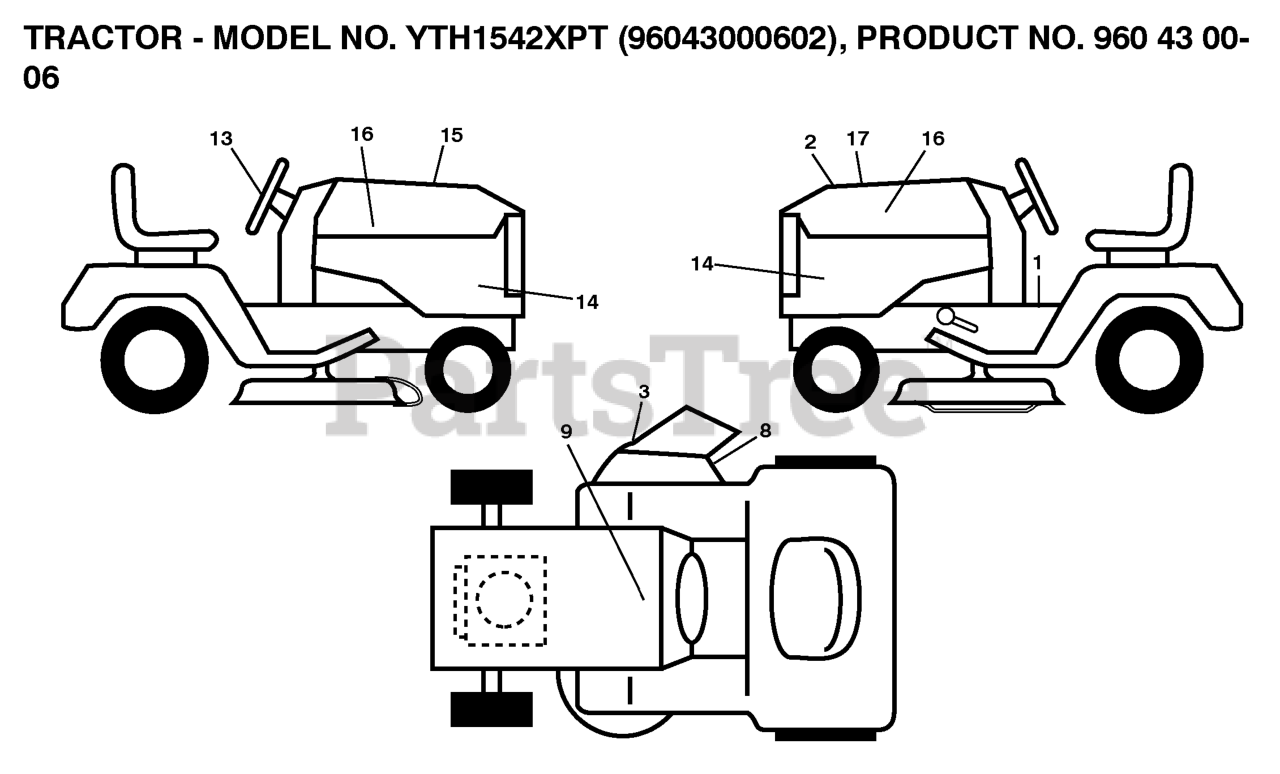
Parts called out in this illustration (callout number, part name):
1	DECAL.FENDER.OPER.TEX.
2	DECAL.HOOD.TOP.INSERT.
3	DECAL.WARN.KEEP.HAND.AWAY
8	DECAL V BELT SCHEMATIC
9	DECAL BTRY SYMBOLS
13	DECAL.WHEEL.STRG.LGN.H
14	DECAL.SDPANEL.YTH1542X
15	DECAL HOOD CUST. RESP.
16	DECAL.HOOD.LOGO.PLAQUE
17	DECAL.RPL.YTH1542XPT.2006
